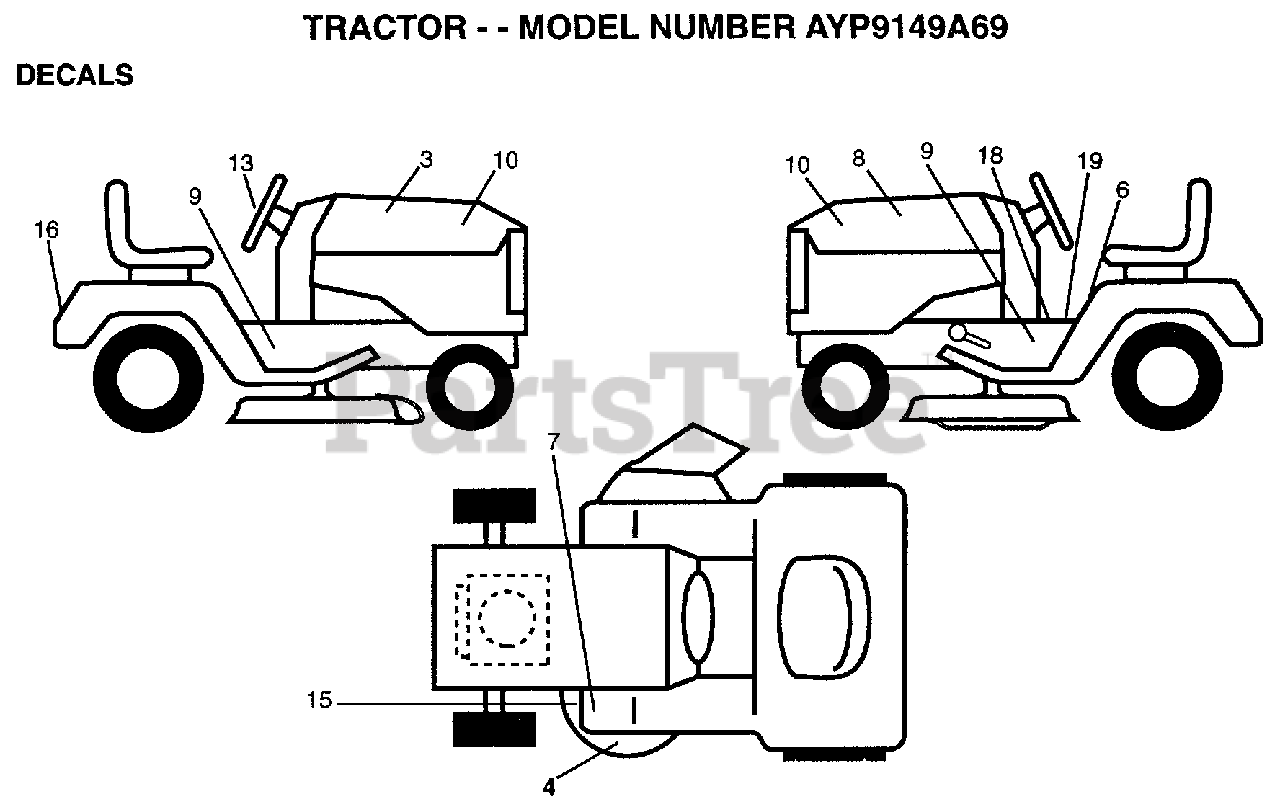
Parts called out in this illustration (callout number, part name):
1	DECAL.FENDER.WIZ
2	DECAL.BATRY.3-3908
3	DECAL.HD.RH.WIZAR
4	DECAL DECK WIZ +
6	DECAL
8	DECAL.HD.LH.WIZAR
9	"DECAL.CHASSIS.42"""
10	DECAL.INS.HD.14.5
13	DECAL.INS.STRG.WL
18	DECAL
18	DECAL SADLE HYDRO
